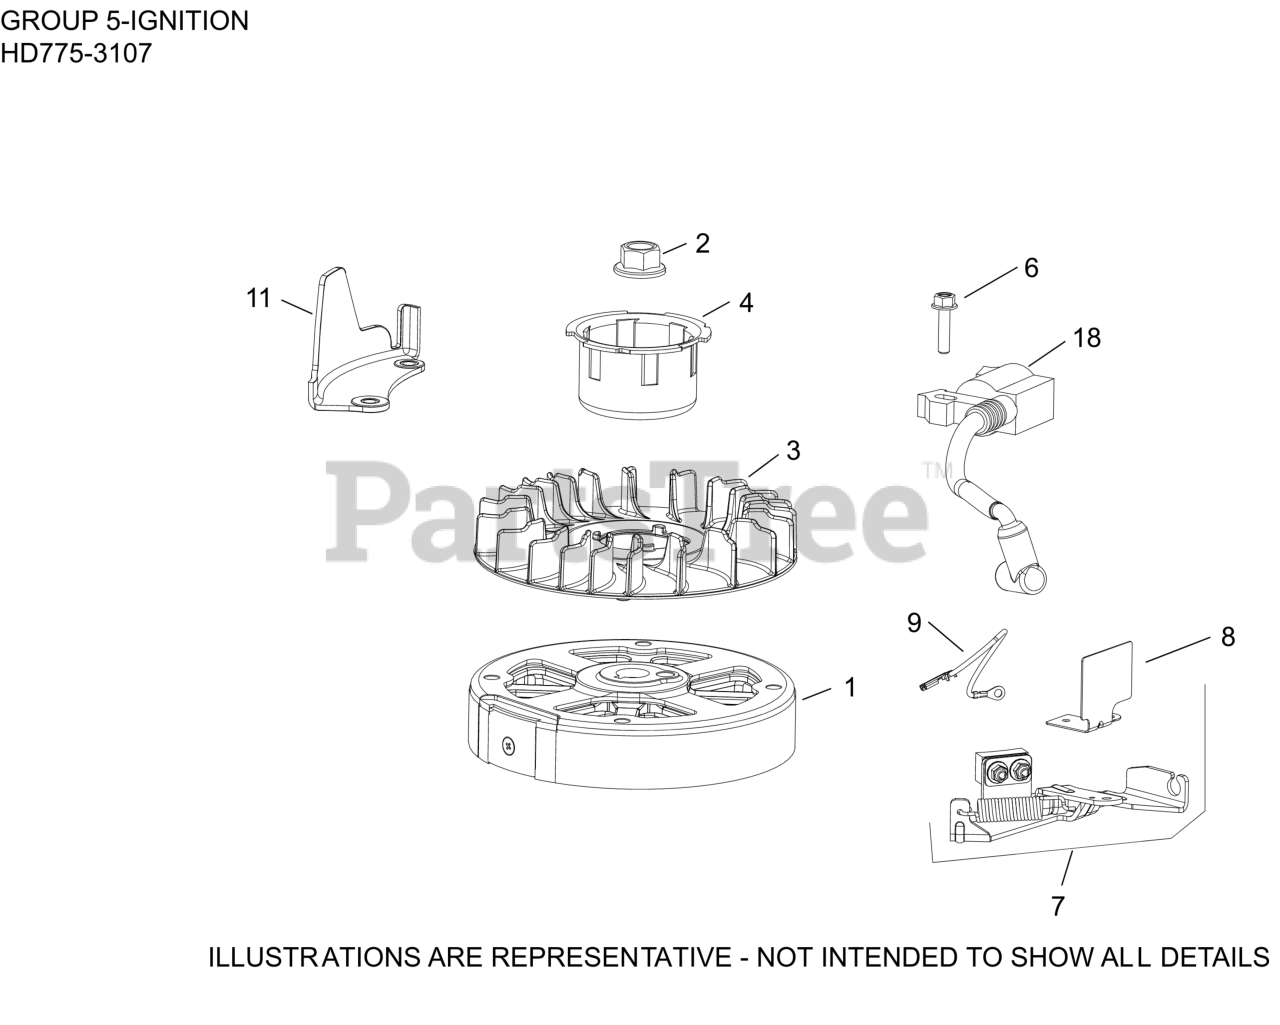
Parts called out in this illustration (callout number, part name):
1	FLYWHEEL ASSEMBLY
2	NUT, FLYWHEEL (W/SERRATIONS)
3	FAN, FLYWHEEL
4	CUP, DRIVE - (#1410905S)
6	SCREW, M6 X 25-(#25086436S)
7	BRAKE ASSEMBLY
8	GUARD, BRAKE - USE 14 314 30-S
9	LEAD, KILL (BRAKE TO IGN. MODULE)
11	GUARD, FINGER
18	MODULE IGNITION CAST IRON FLYWHEEL
